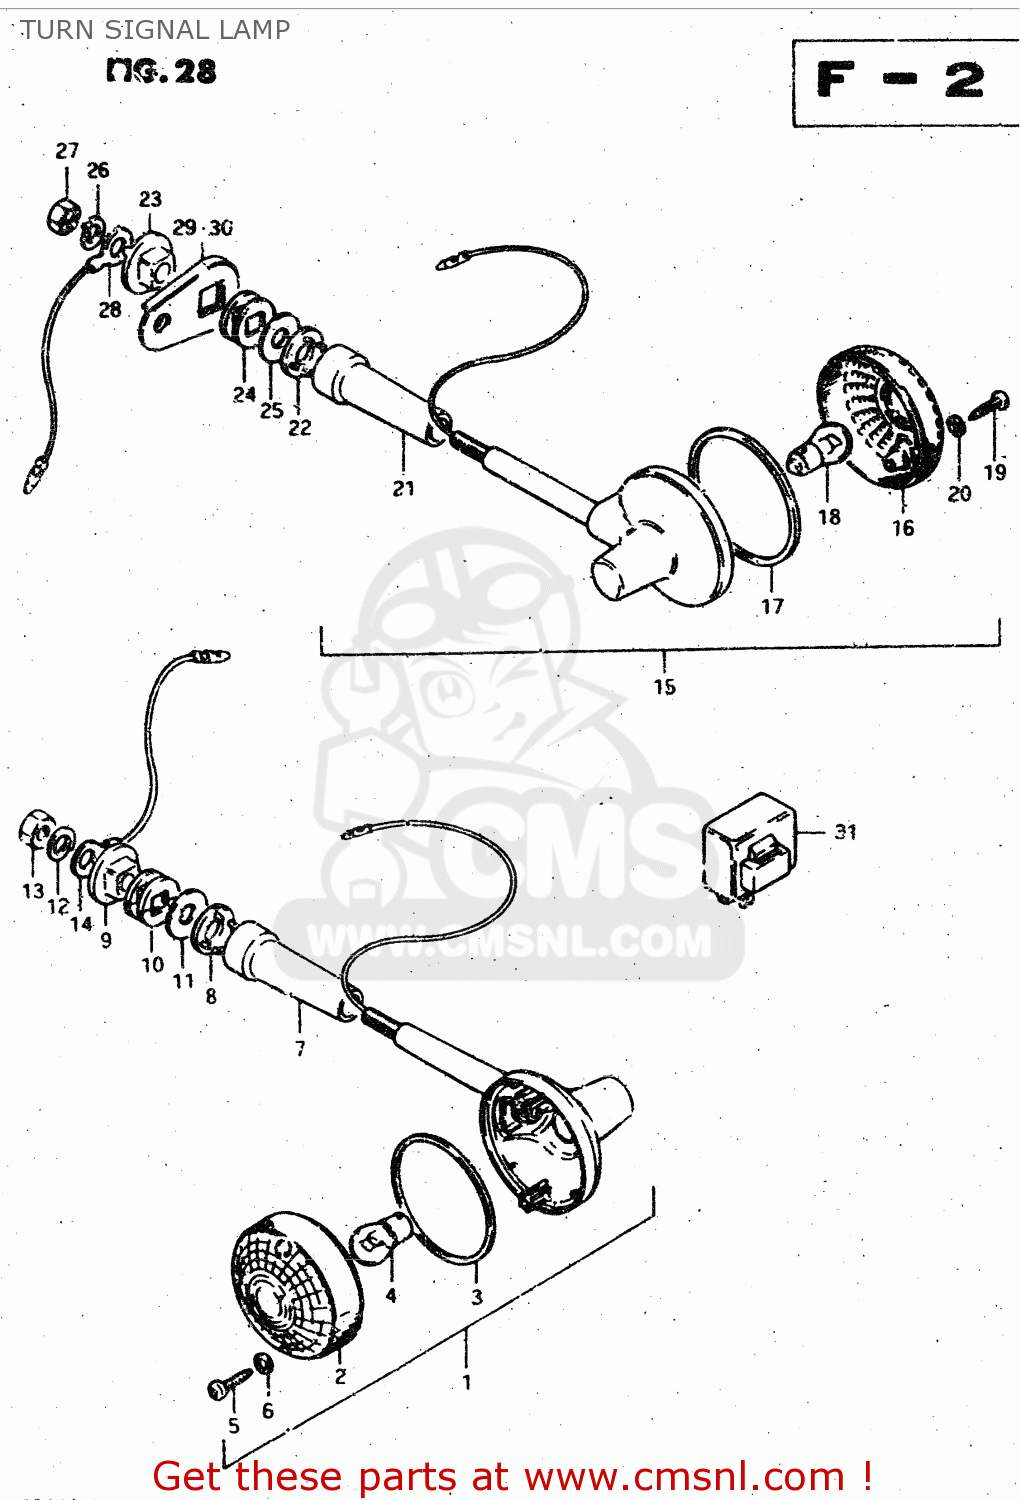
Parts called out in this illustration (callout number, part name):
1	LAMP, REAR TURN SIGNAL
2	LENS
3	GASKET (NAS)
4	BULB(12V21W)
5	SCREW
6	GASKET (NAS)
7	COVER,STAY
8	SPACER
9	SPACER
10	CUSHION
11	WASHER (10.5X30X2.3)
12	LOCK WASHER
13	NUT
14	LEAD WIRE,EARTH
15	LAMP, REAR TURN SIGNAL
16	LENS
17	GASKET (NAS)
18	BULB(12V21W)
19	SCREW
20	GASKET (NAS)
21	COVER,STAY
22	SPACER
23	SPACER
24	CUSHION
25	WASHER (10.5X30X2.3)
26	LOCK WASHER
27	NUT
28	LEAD WIRE,EARTH
29	BRACKET,RR TURN SIGNAL LAMP
30	RELAY,TURN SIGNAL
